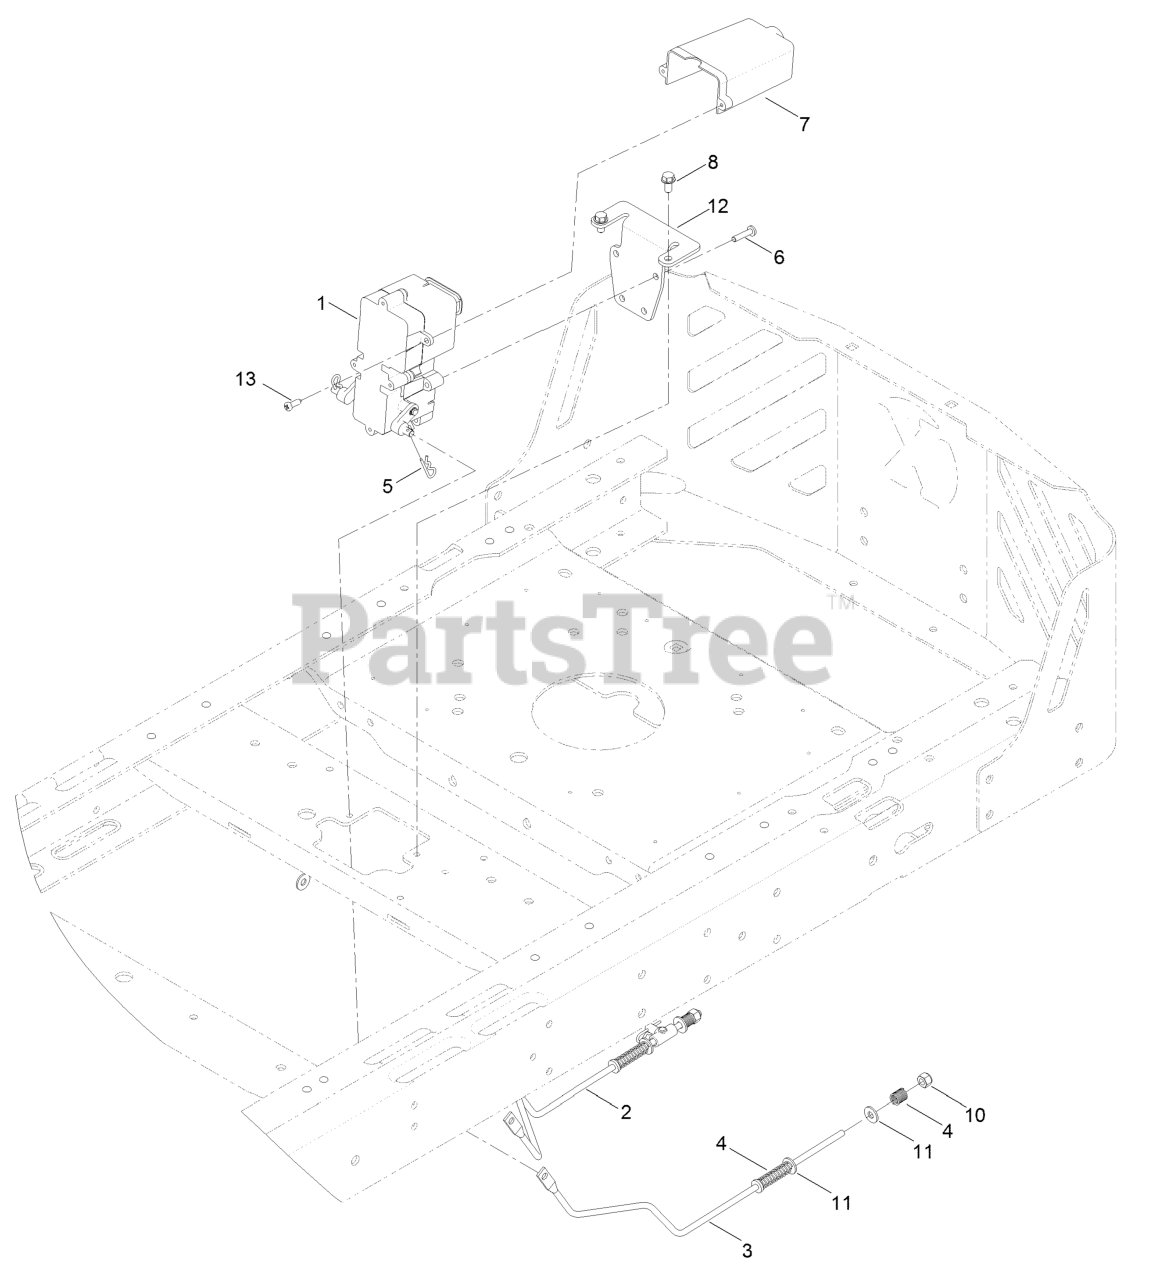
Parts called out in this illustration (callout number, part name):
2	ROD-BRAKE, RH
3	ROD-BRAKE, LH
4	SPRING-COMPRESSION
6	SCREW-PPH
8	SCREW-HWH
10	NUT-LOCK, NI
12	BRACKET-MOUNT, BRAKE
13	SCREW-PPH
